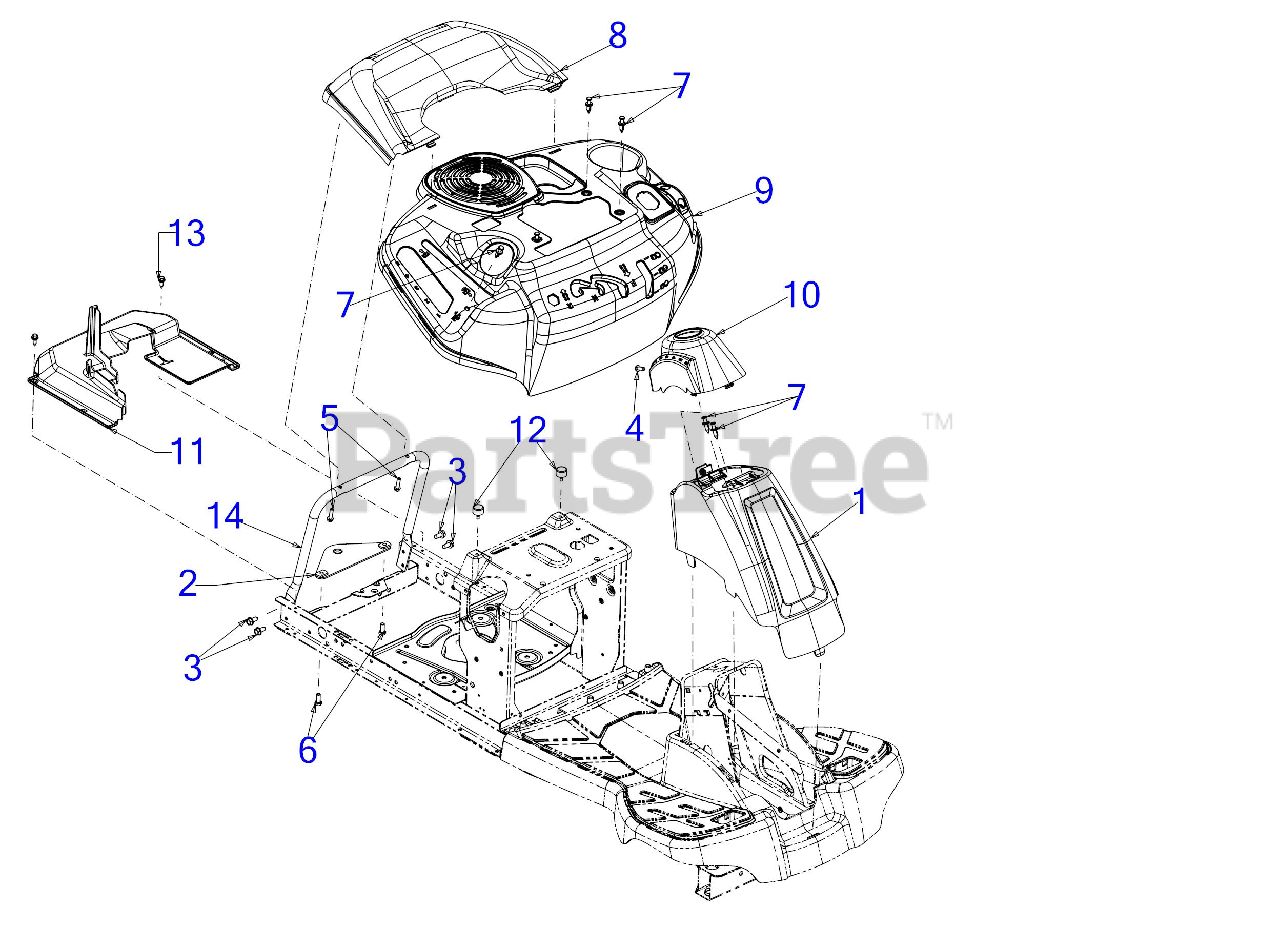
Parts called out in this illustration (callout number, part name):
1	COLUMN COVER ASSEMBLY (MTD RED)
3	SCREW 5/16-18 x .750
4	SCREW 1/4-20X.75
5	SCREW 1/4-15 x 1.00
6	SCREW 5/16-18 x .75 GR5
7	PLASTIC RIVET
8	REAR COVER
10	COLUMN STEERING CAP
11	DRIVE OVER REAR
12	BUMPER .62 DIA x .50
13	SHOULDER SCREW
